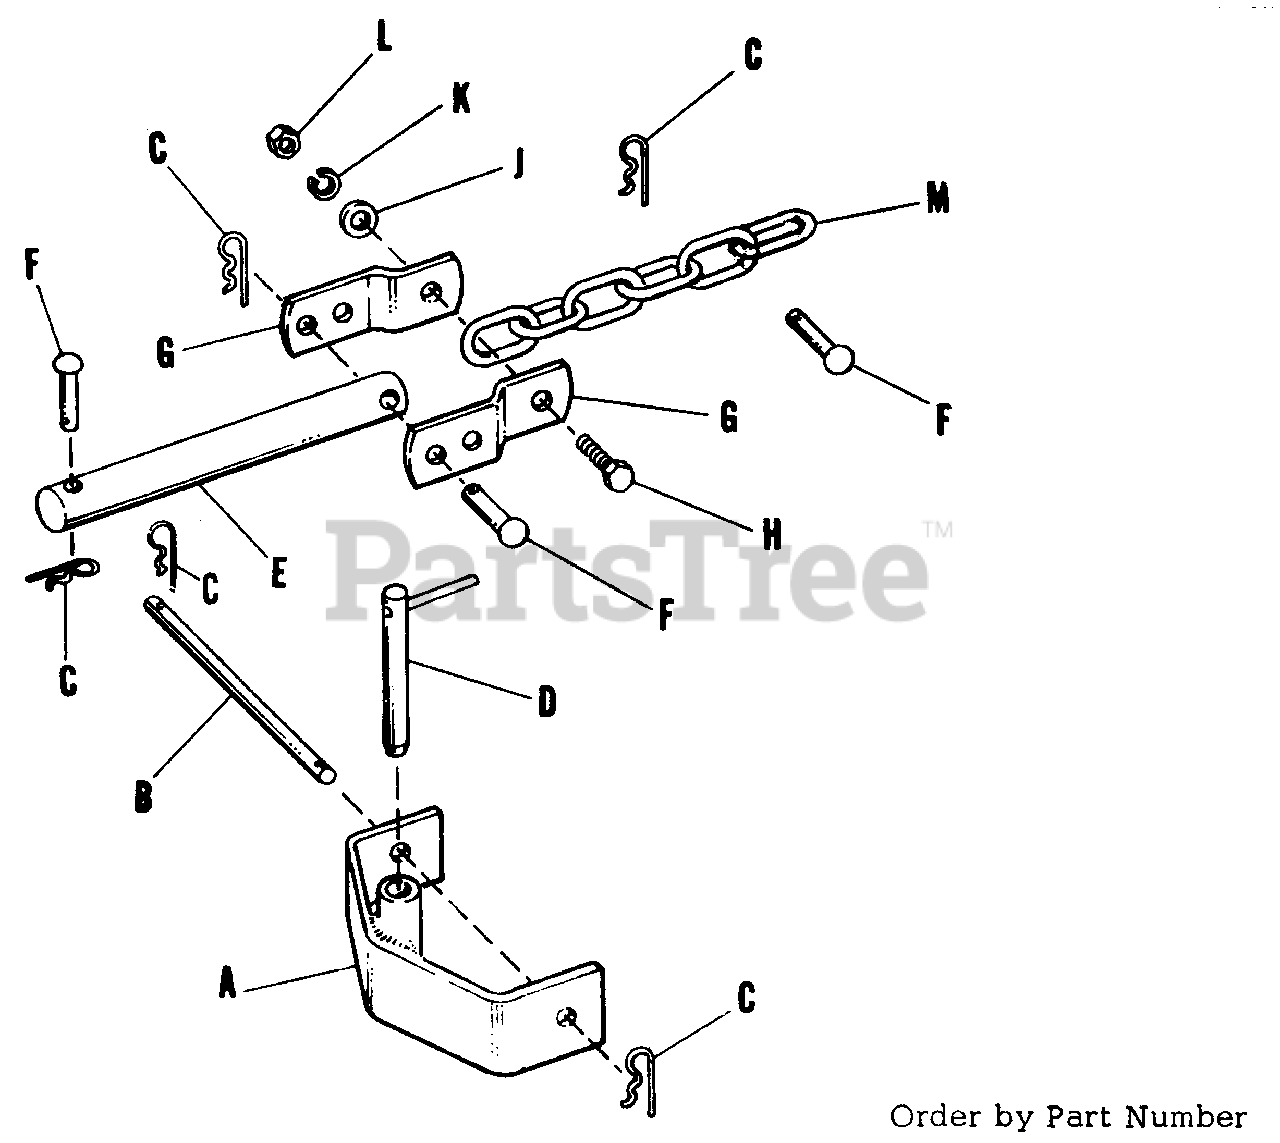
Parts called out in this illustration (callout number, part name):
A	Clevis Assembly
B	Rod, Pivot
C	Clip, Spring
D	Pin Assembly, Hitch
E	Pin, Plow Lift
F	Pin
H	Capscrew, Hex Hd., 3/8"-16 NC x 1 1/2" long
J	Washer, Plain 3/8"
K	Lockwasher, 3/8"
L	Hex Nut, 3/8-16 NC
M	Chain, Plow Lift
